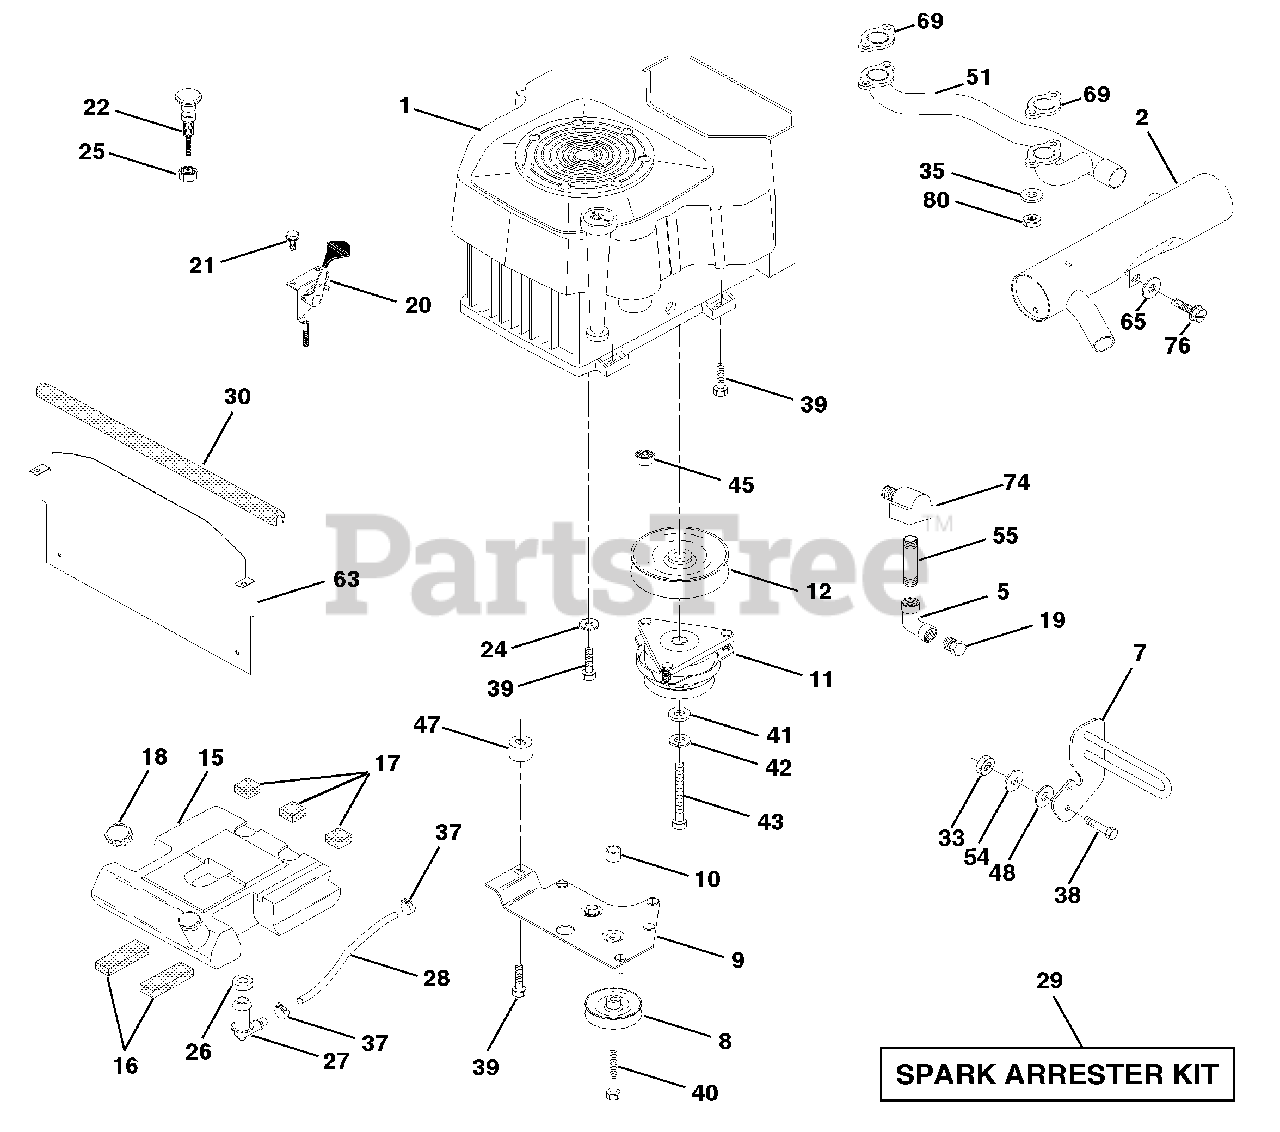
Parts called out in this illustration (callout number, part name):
2	Muffler Side 1-1/8" 98
5	Elbow STD 90 Degree 3/8-18 NPT
7	Muffler Assembly Guard
8	Pulley V-Idler
9	Keeper Asm Belt Engine VGT 96
11	Clutch Electric
12	Pulley Engine VGT Elect Clutch
15	Tank Fuel Rear
16	Pad Spacer
17	Pad Spacer
18	Cap Asm Fuel W/Sym Vented
19	Plug Oil Drain
20	Control Throttle
21	Screw Hex Thd Cut 1/4-20 X 5/8
22	Control Choke
24	Washer Ext Tooth 3/8
25	Nut Keps 3/8 - 24 UNF
26	Bushing
27	Stem Tank Fuel
28	Fuel Line
29	Spark Arrester Kit
30	Extrusion Hood
33	Nut, Hex W/Ins. 3/8-16 UNC
35	Washer Split
37	Clamp Hose
38	Bolt, Fin Hex 3/8-16 UNC x 1-1/2
39	Screw TT 3/8-16 x 2-1/4 UNC
40	Screw TT 3/8-16 x 4 UNC
41	Washer 1-1/2 OD X 15/32 ID X .250
42	Washer Lock 7/16
43	Bolt Hex 7/16-20 X 4-1/4 Ga 5
45	Nut Flange 1/4-20 Starter Nut
47	Spacer Engine
48	Washer 13/32 x 1-1/4 x 7 Ga.
51	Manifold Pipe VGT CV 1-1/8
54	Washer Flat 13/32 x 7/8 x 14 Ga.
55	Nipple, Pipe 4-1/2
63	Shield, Heat VGT YP/Husq.
65	Washer 13/32 x 1 x 14 Ga.
69	Gasket Kohler
74	Elbow Street Brass
76	Screw Thdrol 3/8-16 x 3/4 TY-TT
80	Nut Flange M8-1.25
